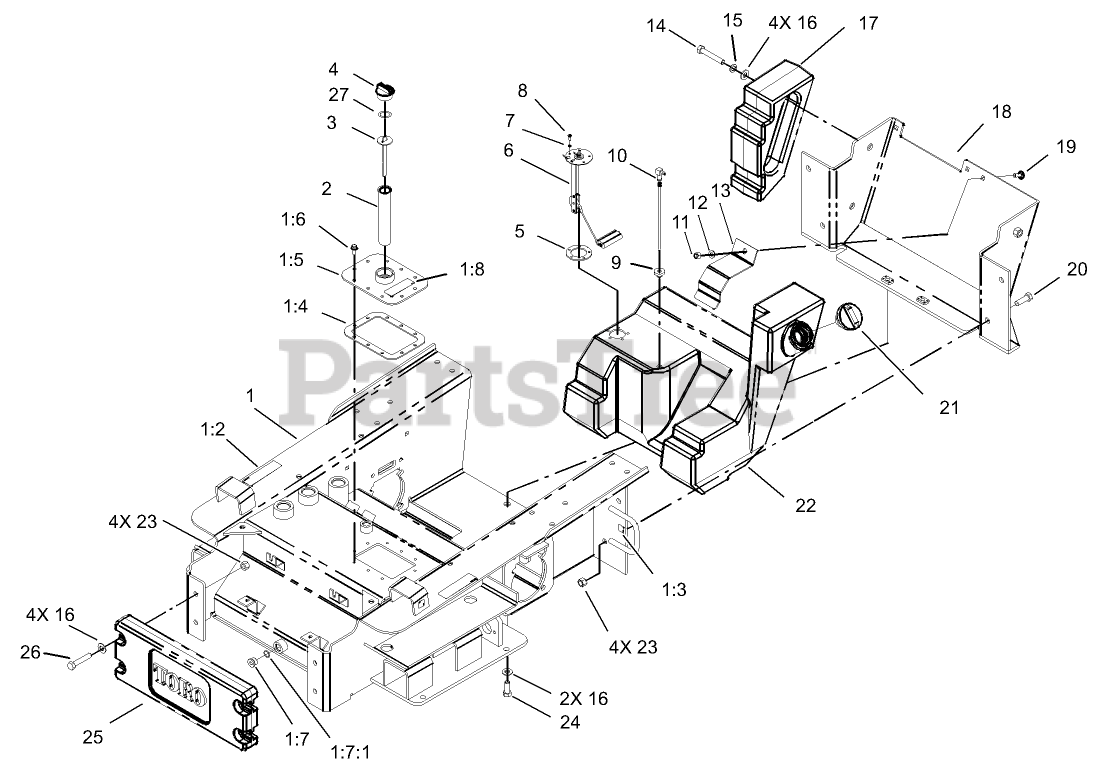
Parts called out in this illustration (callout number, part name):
1	CHASSIS ASM
1:2	DECAL-PINCH
1:3	DECAL-POINT, LIFT
1:4	GASKET-COVER, ACCESS
1:5	TANK COVER ASM
1:6	SCREW
1:7	PLUG-HEX
1:7:1	O-RING
1:8	DECAL-OIL, HYD
2	FILTER-SCREEN
3	DIPSTICK-OIL
4	PLUG-PLASTIC
5	GASKET-SENDER, FUEL
6	SENDER-FUEL
7	WASHER-LOCK
8	SCREW-PPH
9	BUSHING
10	PIPE-STAND
11	NUT-LOCK, NI
12	WASHER-FLAT
13	CLAMP-TANK, FUEL
14	SCREW-HH
15	WASHER-LOCK
16	WASHER-FLAT
17	COUNTERWEIGHT-REAR
18	REAR FRAME COVER ASM
19	SCREW-CARR
20	SCREW-HH
21	CAP-FUEL
22	TANK-FUEL
23	NUT-LOCK, NI
24	SCREW-HH
25	COUNTERWEIGHT-FRONT
26	SCREW-HH
27	O-RING
